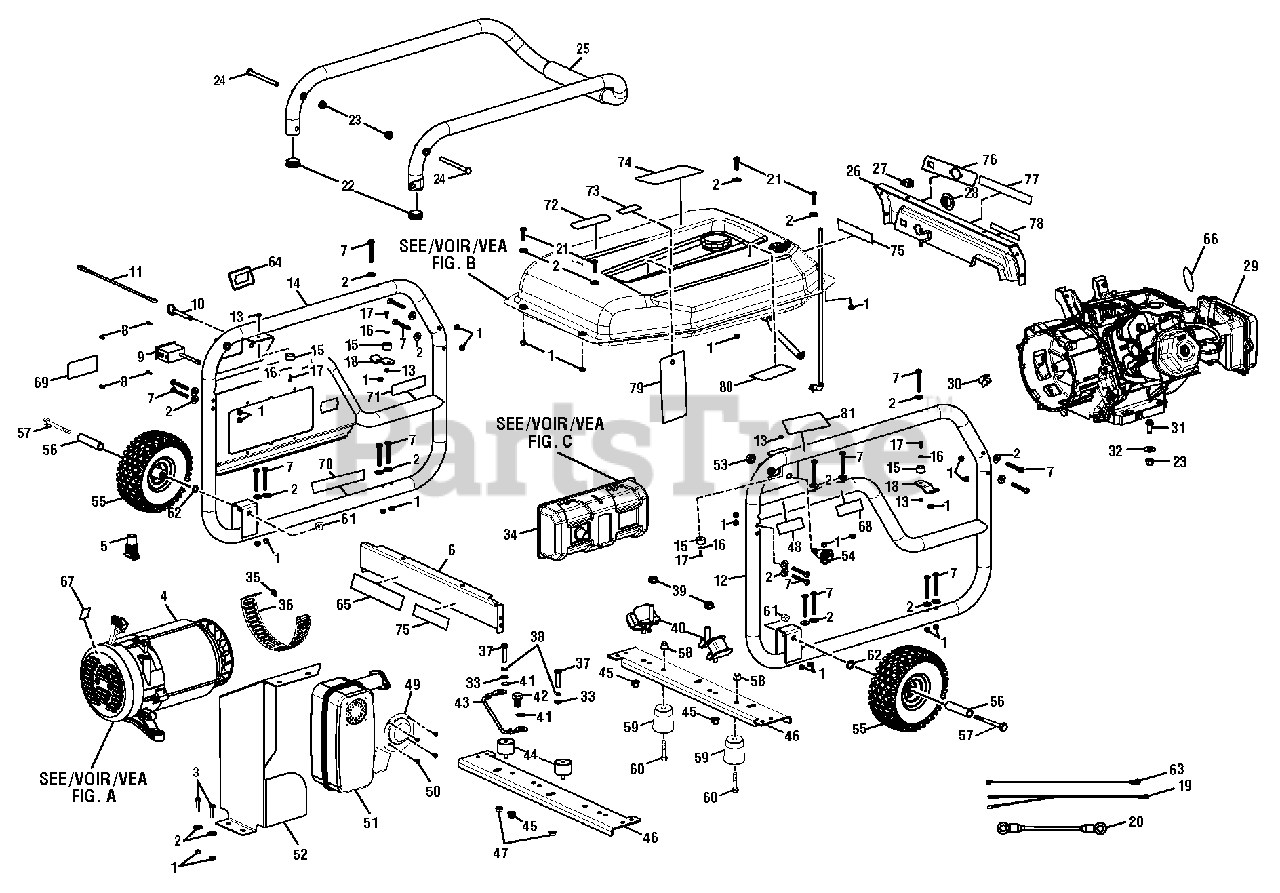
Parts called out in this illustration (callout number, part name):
1	Lock Nut (M6)
2	Washer (1/4 in.)
3	Bolt (M6 x 16 mm, Hex Hd.)
4	Generator Head Assembly (See Figure A)
5	Rubber Boot
6	Fuel Tank Support (Rear)
7	Screw (M6 x 50 mm, Pan Hd.)
8	Screw (6-20 x 3/8 in.)
9	Analog Hour Meter
10	Pin Release
12	Frame (Left)
13	Lock Nut (M4)
14	Frame (Right)
15	Rubber Bumper
16	Washer (M4)
17	Screw (M4 x 12 mm)
18	Handle Bracket
19	Assembly Wire (Black)
20	Bonding Wire
21	Screw (M6 x 25 mm, T-30 Torx Pan Hd.)
22	End Cap (Handle)
23	Lock Nut (M8 x 1.25)
24	Screw (M8 x 98 mm, Flat Hd.)
25	Handle Assembly
26	Fuel Tank Support (Front)
27	On/Off Switch
28	Fuel Valve Bezel
29	Engine (LCT)
30	Rubber Plug
31	Bolt (M8 x 40 mm, Hex Hd.)
32	Washer (5/16)
33	Washer (M8)
34	Control Panel Assembly (See Fig. C)
35	Bolt (M5 x 10 mm, Hex Hd.)
36	Fan Cover
37	Bolt (5/16-18 x 1.5 in., Hex Hd.)
38	Lock Washer (M8)
39	Lock Nut (M10)
40	Isolator (Large)
41	Star Washer (M8)
42	Bolt (M8 x 15 mm, Hex Hd.)
43	Ground Wire Assembly
44	Isolator (Small)
45	Flange Nut (M8)
46	Reversible Cross Plate
47	Hex Nut (5/16-18)
48	Combustion Label
49	Spark Arrestor Screen
50	Screw (8-32 x 3/8 in., Pan Hd.)
52	Heat Shield
53	Hex Nut (1/2-20)
54	Handle Lock Assembly
57	Axle Bolt
58	Lock Nut (M8 x 1.25)
59	Rubber Foot
60	Bolt (M8 x 45 mm, Hex Hd.)
61	Lock Nut (M10)
62	Washer (M10)
63	Wire Assembly (Green)
64	Systems Monitor Label
65	Ground Warning Label
66	Recoil Housing Label
67	Ground Label
68	Hot Surface Label
69	Lock and Pin Label
70	Lubricant Label
71	Inquires label
72	Fire Danger Label
73	E85 Label
74	CPSC Label
75	Fire Distance Label
76	Fuel Label
77	Logo Label
78	Start Label
79	Warning Hang Tag
80	Danger Label
81	Handle Release Label
82	Wire Sleeve
